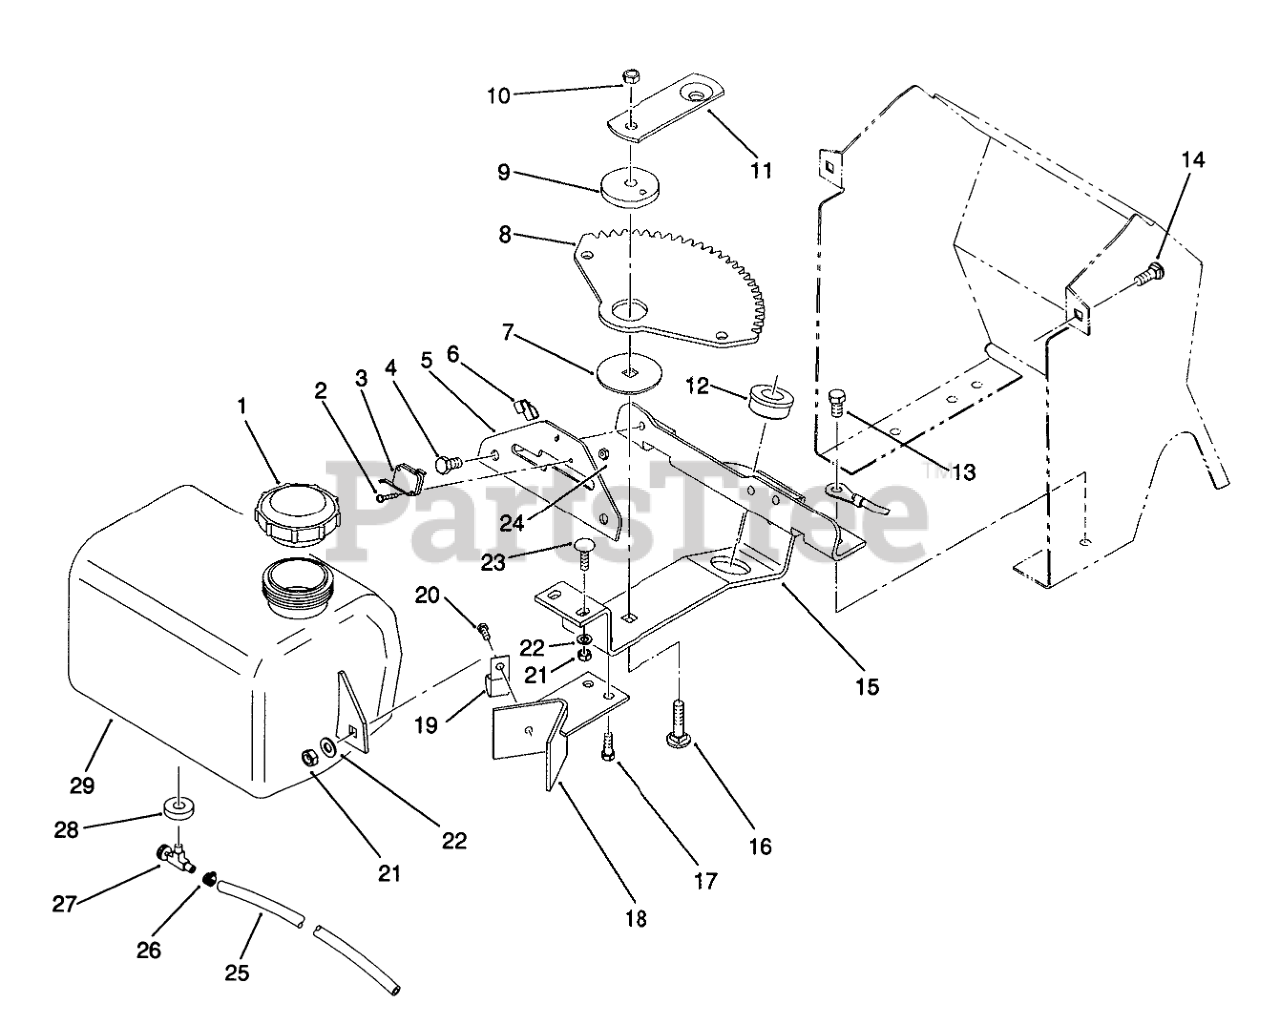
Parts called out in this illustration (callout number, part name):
1	CAP GAS
2	SCREW-PPH
3	SWITCH - CLUTCH
4	Bolt
5	PLATE SHIFT R
6	J-CLIP
7	WASHER-BEARING
8	GEAR-SECTOR
9	BUSHING
11	Plate
12	BEARING-WHEEL
13	Bolt
14	Bolt-Carriage
15	Bracket-Steering
16	Bolt-Carriage
17	Screw
18	Stop-W.A.
19	CLIP
20	Screw
21	Nut
22	Washer
23	Bolt-Carriage
24	NUT-HEX
25	Line-Fuel
26	Clamp
27	VALVE-FUEL
28	BUSHING
29	Fuel Tank
